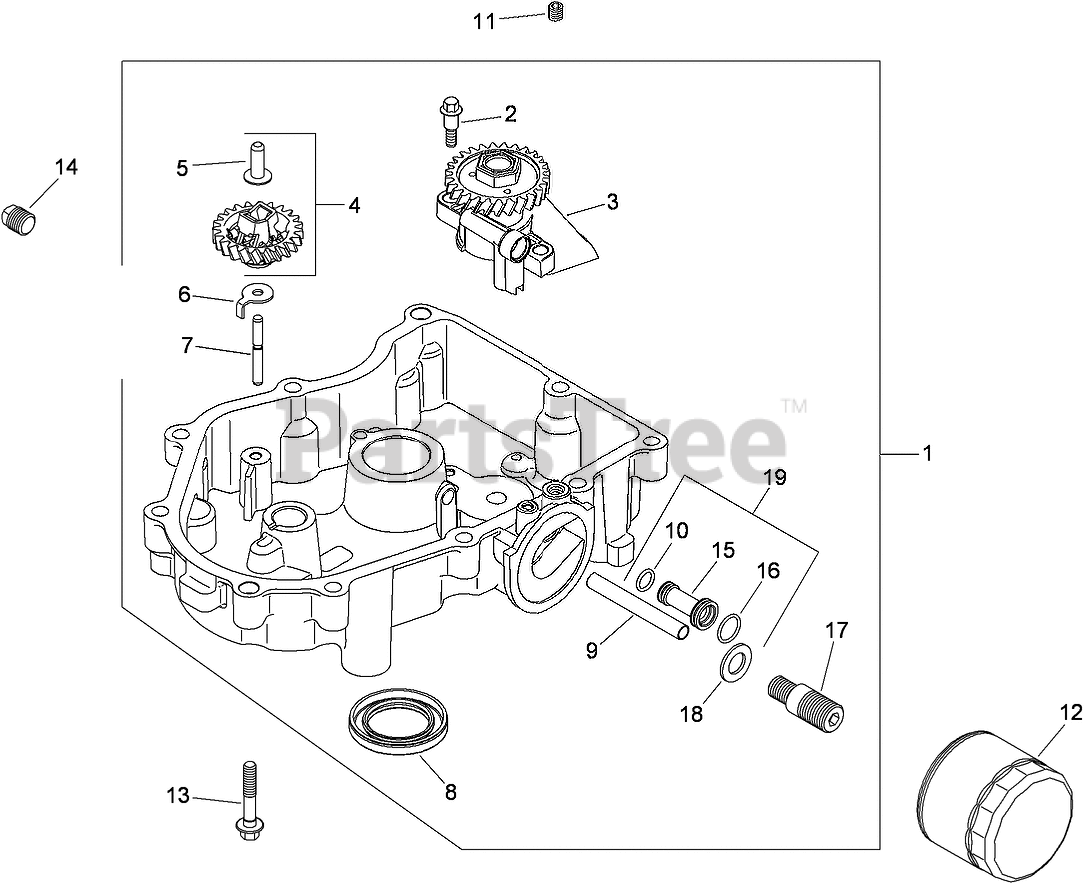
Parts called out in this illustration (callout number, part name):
1	GOVERNOR GEAR W/PIN KIT (INCLUDES REF 2-10, 15-19)
2	SCREW-SHOULDER, THD FRM (M6x1.0x26.5)
3	OIL PUMP ASM
4	GOVERNOR GEAR W/PIN KIT (INCLUDES REF 5)
5	PIN-REGULATING, GOVERNOR
6	TAB-LOCKING
7	SHAFT-GEAR, GOVERNOR
8	SEAL-OIL
9	TUBE-FEED, OIL (FILTER TO PAN)
10	O-RING
11	PLUG-PIPE, COUNTERSUNK (1/8)
12	FILTER-OIL
13	SCREW-FLANGE (M8X1.25X45)
14	PLUG-PIPE, SQ HD (3/8)
15	TUBE-FEED, OIL
16	O-RING
17	NIPPLE-FILTER, OIL
18	WASHER-FLAT
19	OIL FEED TUBE ASM (INCLUDES REF 10, 15, 16)
